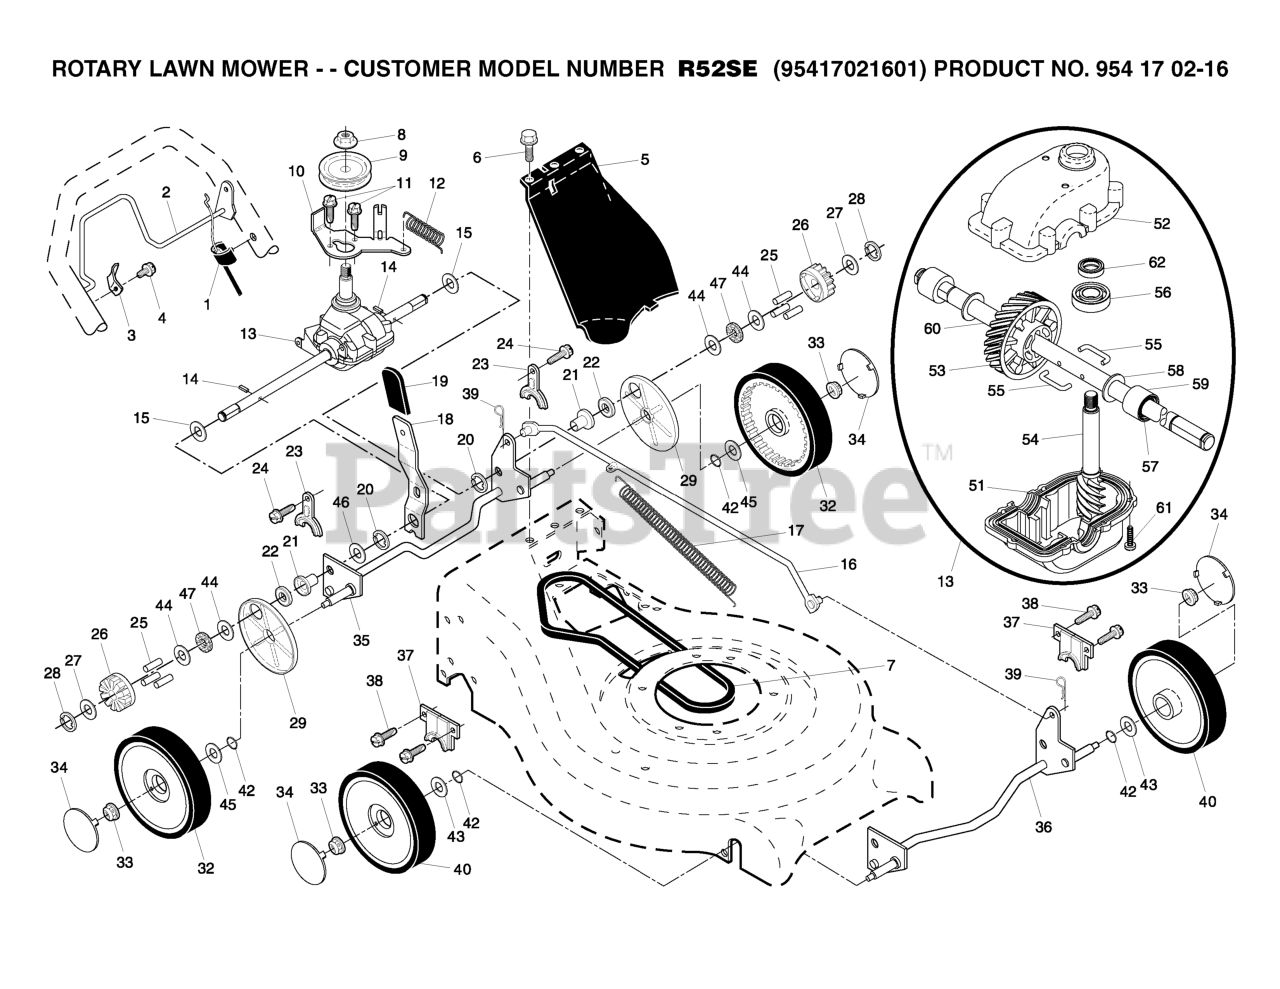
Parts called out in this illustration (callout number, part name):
1	DRIVE CABLE
3	DOWNSTOP BRACKET
8	FLANGED LOCKNUT 3/8-16 ZINC
10	BELT GUIDE
13	TRANSMISSION.21.RWGD.FRANCE
14	PIN.SPRING.THRUST
15	THRUST WASHER
16	ROD CONNECTING
17	SPRING
18	SPRING.SELECTOR.SPT.21
19	KNOB.EXT.ERGO.BLACK
21	RP BEARING SUPPORT
22	BEARING, BALL
23	BRACKET
25	PAWL.DRIVE.ETCHED
26	PINION.DRIVE.WALK
28	E-RING 7/16 RE
29	COVER.DUST.WHEEL
32	WHEEL 9X2
33	WHEEL.9X2.PR.LP.RADIAL.BK.BB.3
34	HUBCAP
35	SHAFT.ASM.REAR.TORQUE
36	SHAFT ASSY FRONT
37	RETAINER.FRONT.SHAFT
39	RETAINER CLIP
40	WHEEL ASMBLY FRONT
42	O-RING
43	WASHER.FLAT.1/2
44	WASHER.BELLEVILLE (3 2 LB)
45	WASHER FLUT
46	WASHER.ZINC.PLATED
51	CASE, LOWER
52	GEARCASE.HOUSING
53	GEAR.24.TOOTH.WALK.MOWER
54	SHAFT INPUT
55	WIRE, FORMED (15966)
57	SEAL.OUTPUT.SHAFT
62	SEAL INPUT SHAFT
